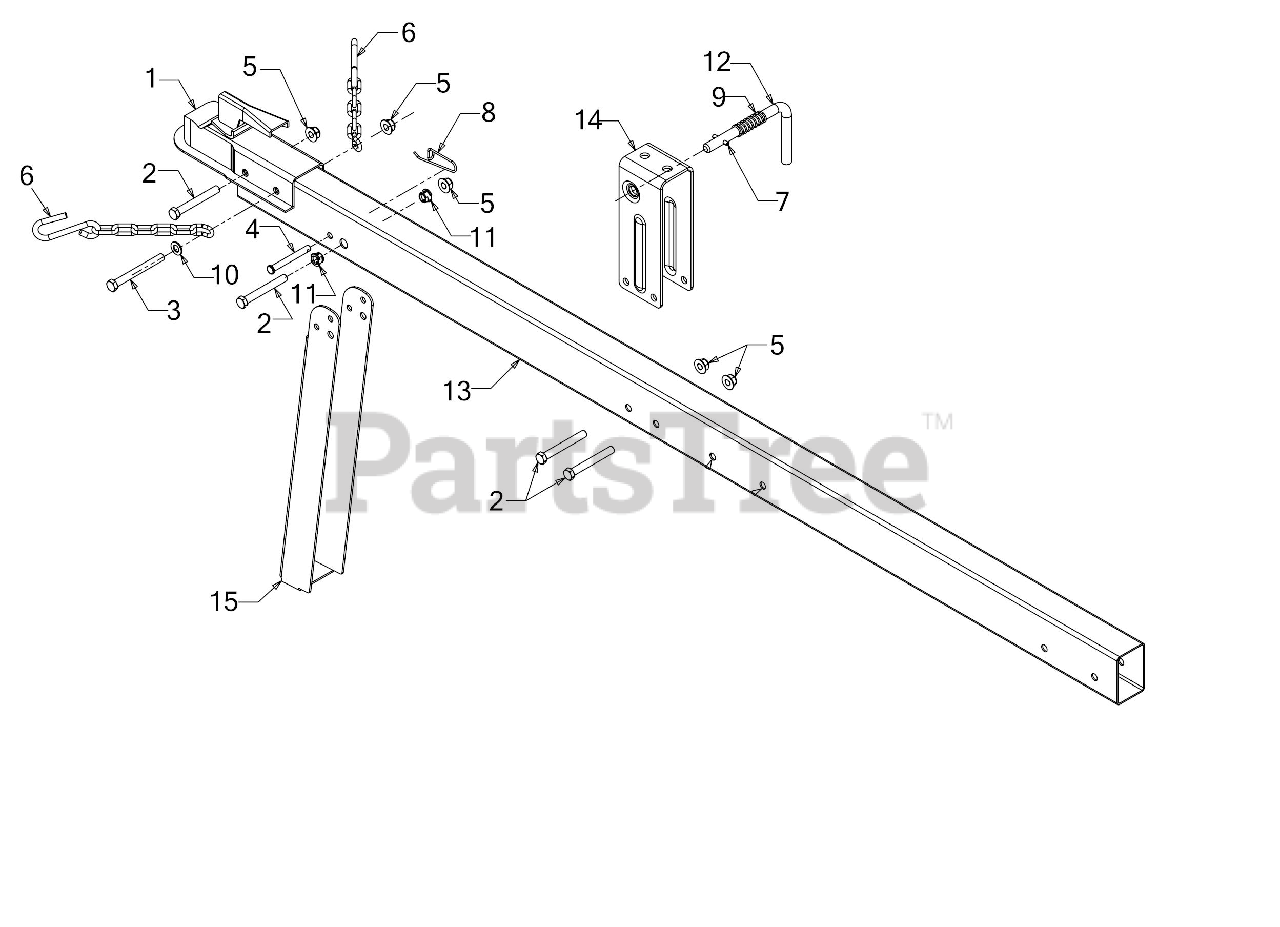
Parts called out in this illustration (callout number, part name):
1	HITCH COUPLING ASSEMBLY
2	SCREW 3/8-16 x 3 GR8
3	SCREW 3/8-16 x 3.50 GR5
4	CLEVIS PIN 5/16 x 2.5
6	LOGSPLITTER TOW CHAIN
7	SPRING PIN 3/16 x 1.00
8	SPRING PIN
9	COMPRESSION SPRING
10	FLAT WASHER
11	BUSHING .380 ID
12	LATCH ROD
